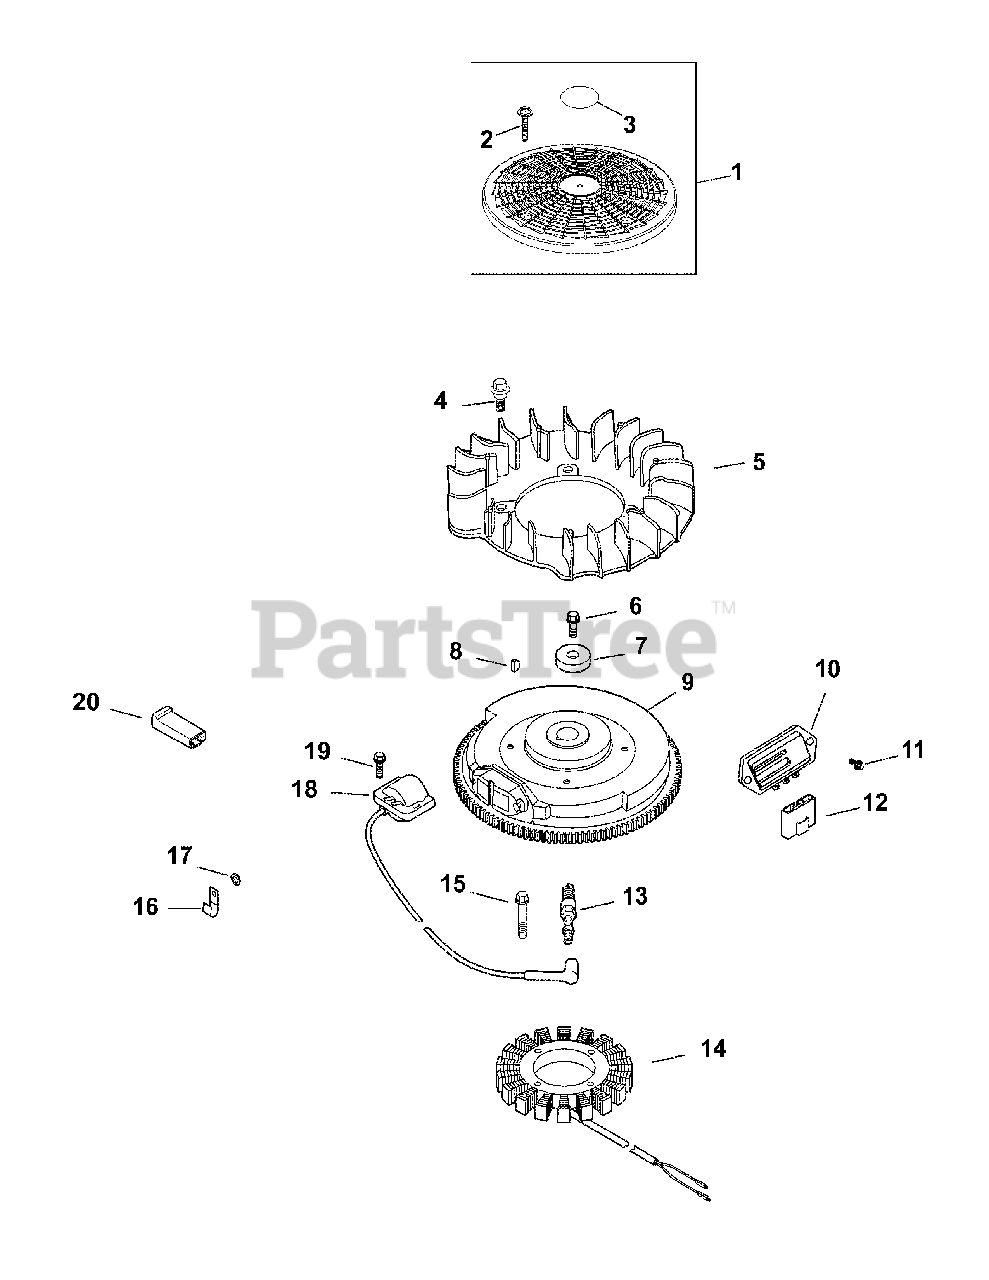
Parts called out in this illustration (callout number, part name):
1	Kit, Grass Screen
2	Screw, Flg Sems M4 x 0.7 x 25
3	Decal, Grass Screen
4	Bolt, Shoulder
6	Screw, FLG M10X1.5X45
7	Washer, Flat 13/32"
8	Key, 3/16" x 5/8"
10	Rectifier-Regulator
11	Screw, Hex Flange Hi-Lo
13	Plug, Spark
14	Kit, 15 Amp Stator
15	Screw, THD FRM M5 x 0.8 x 25
16	Clip, Cable
17	Washer, Flat, 1/4"
18	Kit, Module, Ignition
19	Screw, FLG THD FRM M5 x 0.8 x 20
20	Connector
